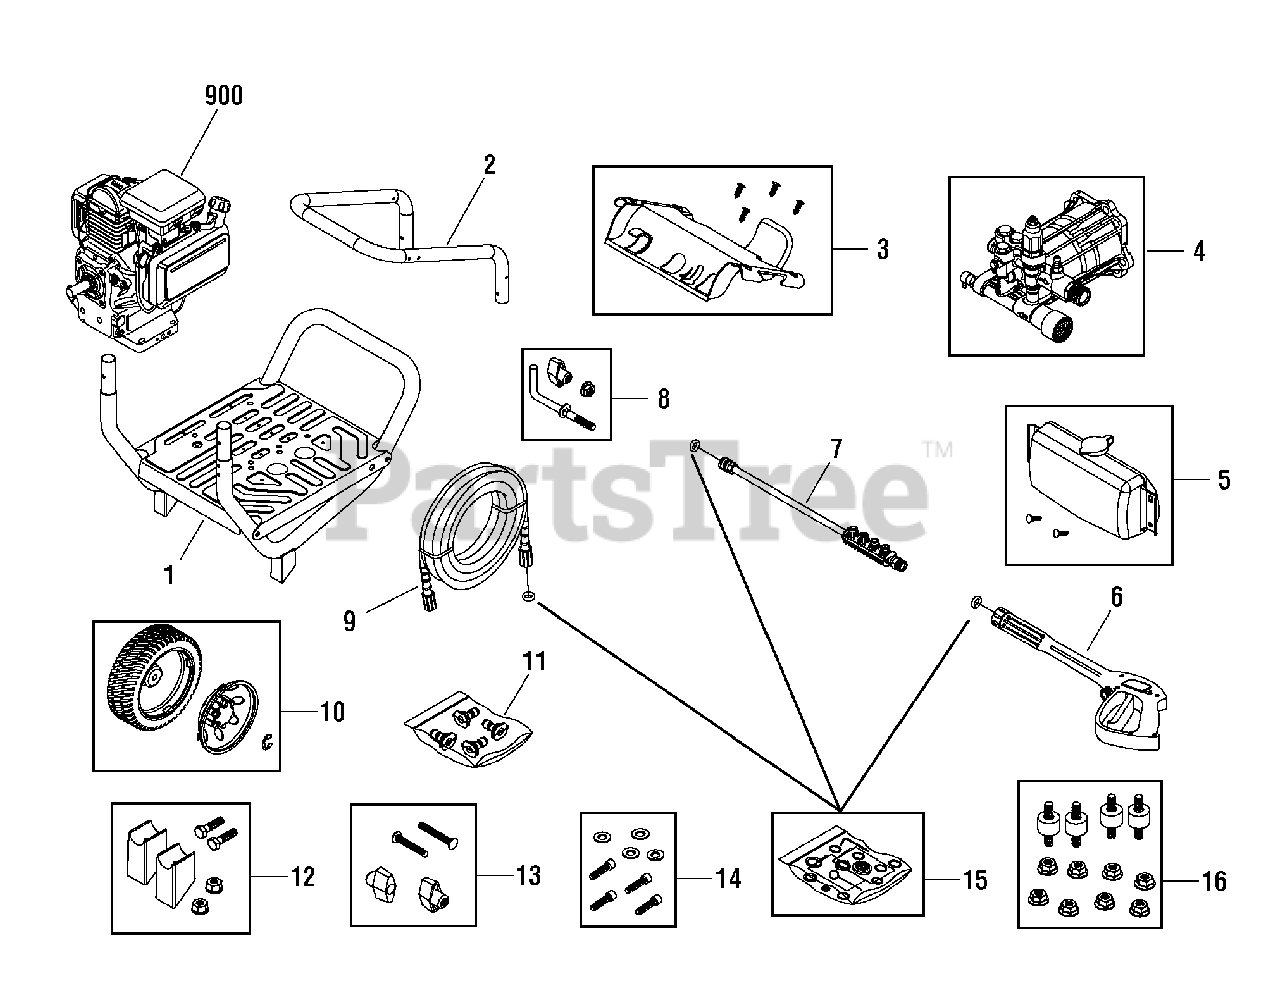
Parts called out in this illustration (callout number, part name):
6	GUN
7	EXTENSION, QC
9	HOSE
11	KIT, QC Nozzles
12	MOUNT, Vibration
13	KIT, Hardware, Handle
14	KIT, Hardware, Pump Mounting
15	KIT, O-Ring
16	KIT, Vibration Mount
900	* ENGINE
